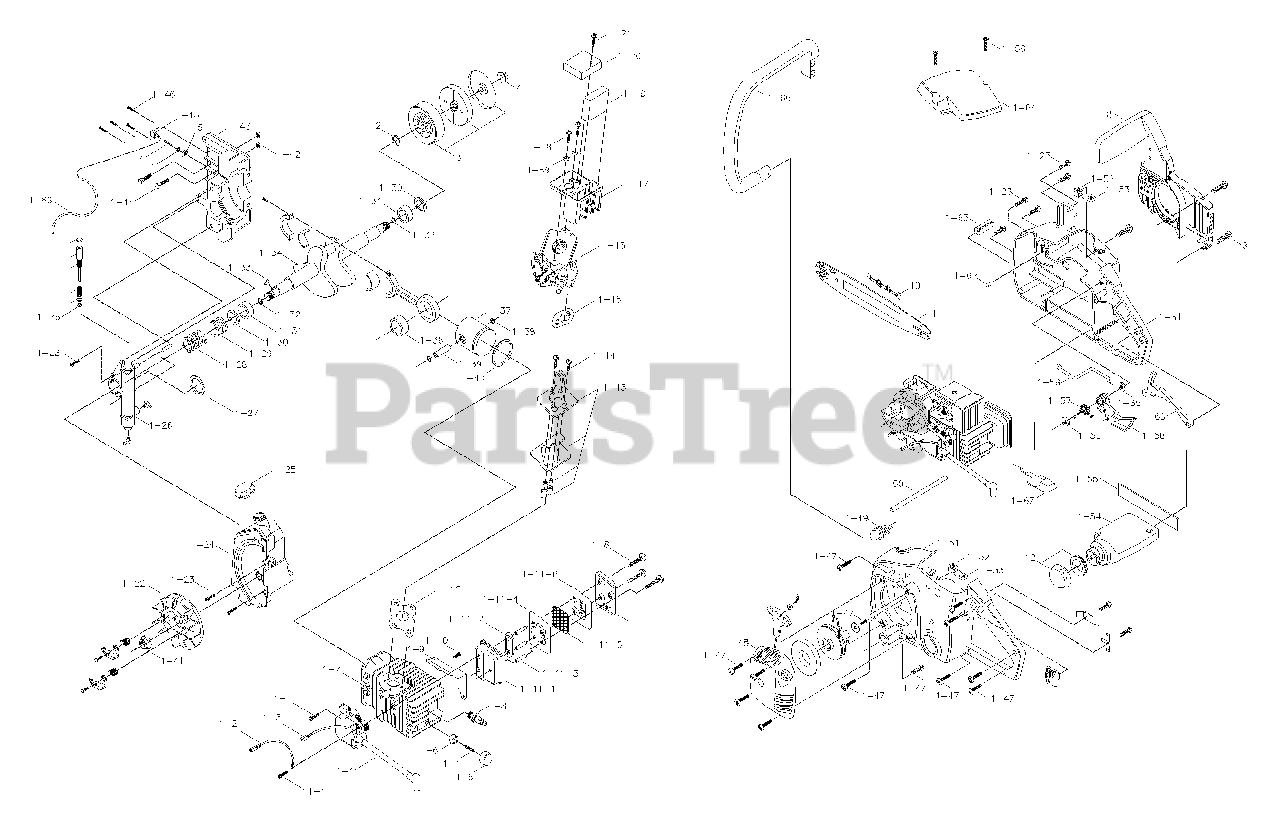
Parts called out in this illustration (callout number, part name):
1	ENGINE ASS'Y
1-2	WIRE, GROUND
1-3	WIRE, STOP SWITCH
1-4	IGNITION ASS'Y
1-5	COVER, CYLINDER
1-6	COVER, SPACER
1-9	BAFFLE, AIR
1-11	MUFFLER ASS'Y
1-11-1	COVER, MUFFLER
1-11-2	PLATE, REINFORCING
1-11-3	SPACER, MUFFLER
1-11-4	BAFFLE, OUTER
1-11-5	BAFFLER, INNER MUFFLER
1-11-6	SCREEN, SPARK ARRESTER
1-11-7	COVER, MUFFLER
1-12	GASKET, INSULATOR
1-13	INSULATOR ASS'Y
1-16	CARBURETOR
1-17	BOX, AIR FILTER
1-18	SCREW
1-19	FILTER, AIR
1-20	SHIELD, CARBURTER
1-22	FLYWHEEL ASS'Y
1-24	FUEL TANK ASS'Y
1-25	CAP, FUEL ASS'Y
1-26	OIL PUMP ASS'U
1-29	WORM GEAR
1-30	SEAL, C'SHAFT OIL
1-33	KEY, FLYWHEEL
1-34	CRANKSHAFT ASS'Y
1-37	PISTON
1-40	PISTON RING
1-42	NUT-RETAINING
1-44	SCREW, BAR
1-46	HEX SCREW WASHE
1-48	STARTOR HOUSING ASS'Y
1-51	ENGINE HOUSING
1-52	RETAINER, NUT
1-54	OIL TANK ASS'Y
1-55	SPACER, OIL TANK
1-58	TRIGGER, THROTTLE
1-59	ROD, THROTTLE
1-60	LATCH, THROTTLE
1-61	HOUSING, RIGHT
1-62	FILTER, FOAM
1-64	COVER, AIR FILTER
1-67	SLIDE, CHOKE
3	DRUM ASS'Y
6	RING, RETAINING
8	BRAKE KIT ASS'Y
12	OIL CAP ASS'Y
